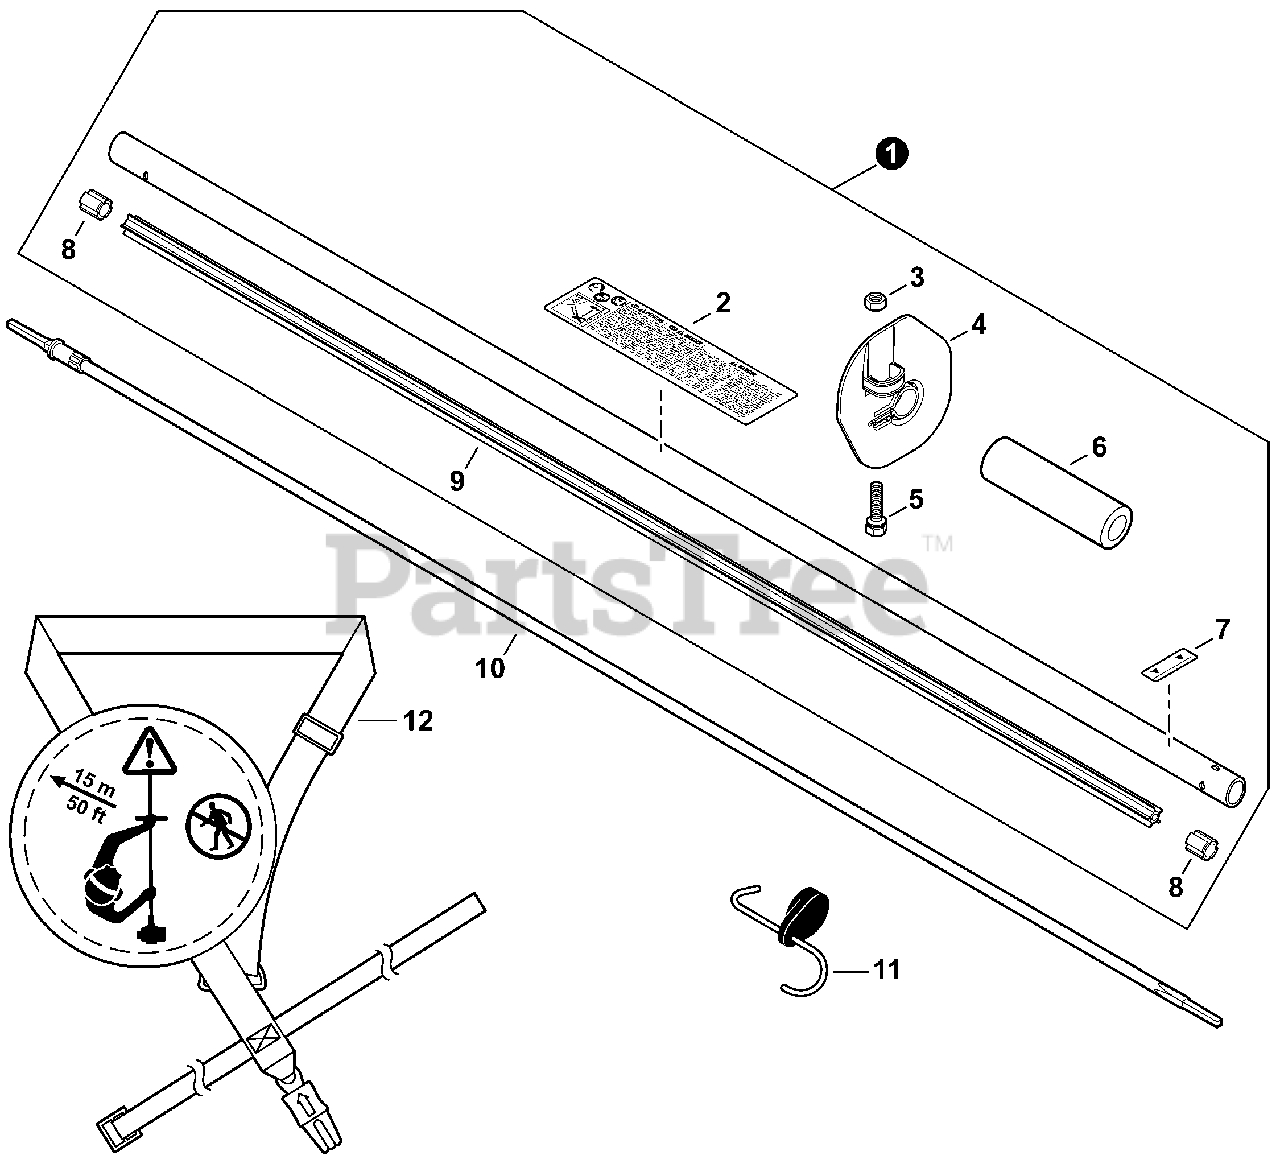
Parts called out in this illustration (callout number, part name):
1	MAIN PIPE ASSY
2	LABEL, CAUTION
3	NUT M5
4	GUARD, HAND
5	BOLT 5×20
6	GRIP, HANDLE
7	LABEL - ALIGNMENT
9	LINER - FLEXIBLE
10	DRIVESHAFT - FLEXIBLE
11	HANGER, ATTACHMENT
12	HARNESS, SHOULDER
